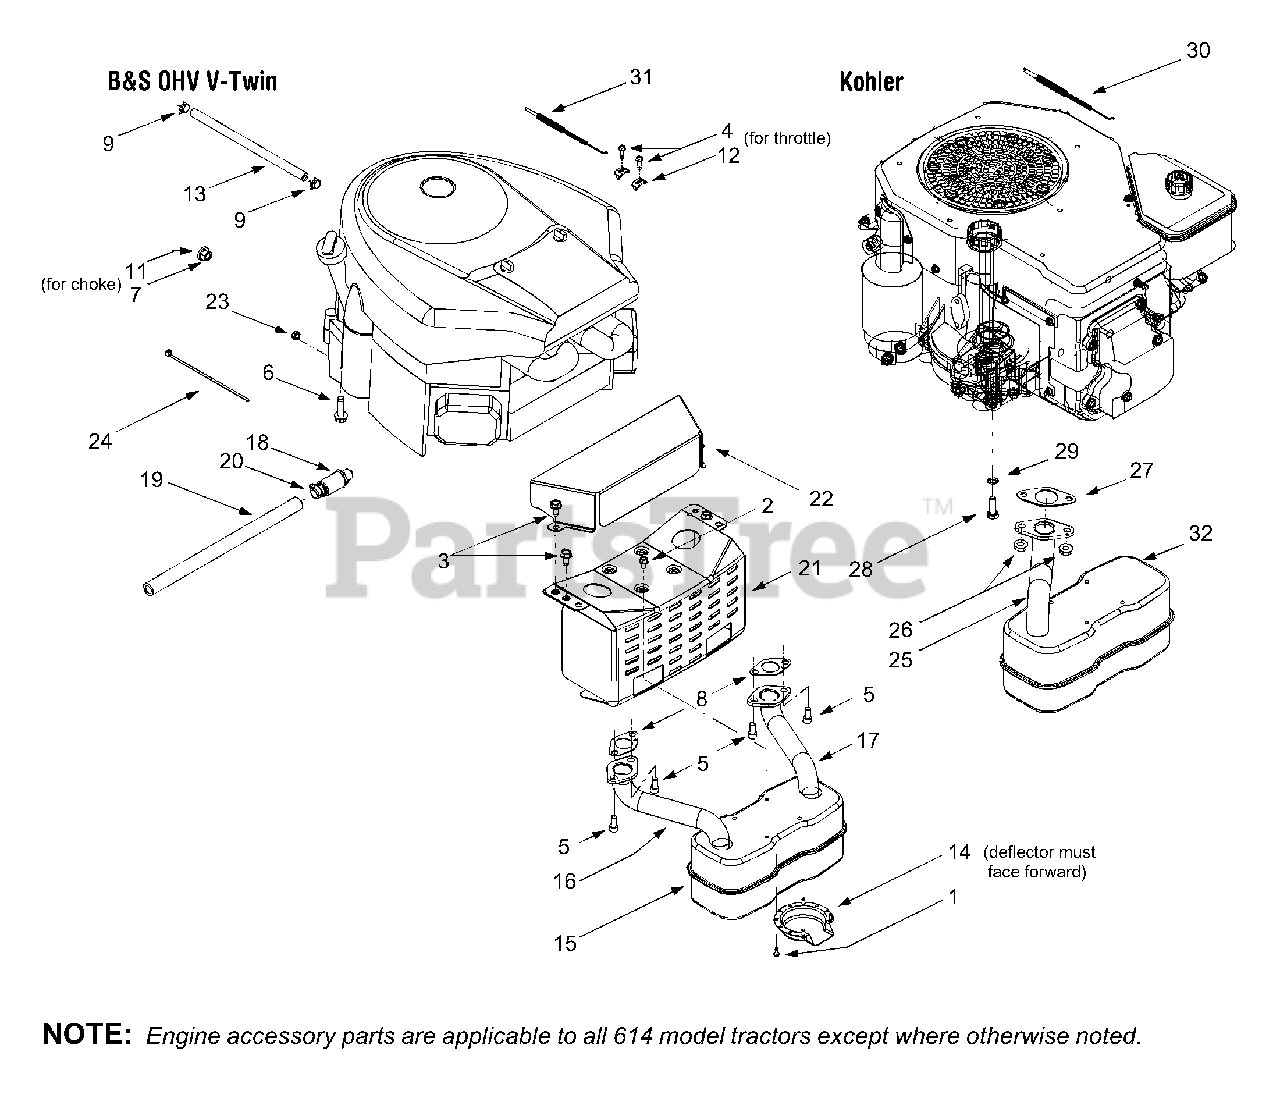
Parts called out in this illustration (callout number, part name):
1	Self-tapping Screw, #8-18 x.50
2	Self-tapping Screw, 1/4-20 x.50
3	Self-tapping Screw, 5/16-18 x.625
4	Screw, #10-32 x.625 (B&S OHV V-Twin)
5	Socket Cap Screw, 5/16-18 x.625
6	Self-tapping Screw, 3/8-16 x 1.25
7	Hex Nut, 3/8-16
8	Exhaust Gasket (B&S OHV V-Twin)
9	Hose Clamp
10	Casing Clamp (B&S OHV Single)
11	Lock Washer,.406 x.875 x.059
12	Casing Clamp (B&S OHV V-Twin)
13	Fuel Line Hose
14	Muffler Deflector
15	Muffler, Twin Inlet (B&S OHV V-Twin)
16	RH Exhaust Pipe (B&S OHV V-Twin)
17	LH Exhaust Pipe (B&S OHV V-Twin)
18	Oil Drain Valve
19	Oil Drain Hose
20	Oil Drain Cap
22	Engine Heat Shield (B&S OHV V-Twin)
23	Hex Sems Nut, 1/4-20 (B&S OHV V-Twin)
24	Cable Tie
25	Exhaust Pipe (Kohler)
26	Flange Nut, 8mm (Kohler)
27	Exhaust Gasket (Kohler)
28	Hex Cap Screw, 8mm (Kohler)
29	External Lock Washer (Kohler)
30	Throttle Cable (Kohler)
31	Throttle Cable (B&S OHV V-Twin)
32	Muffler, Single Inlet (Kohler)
